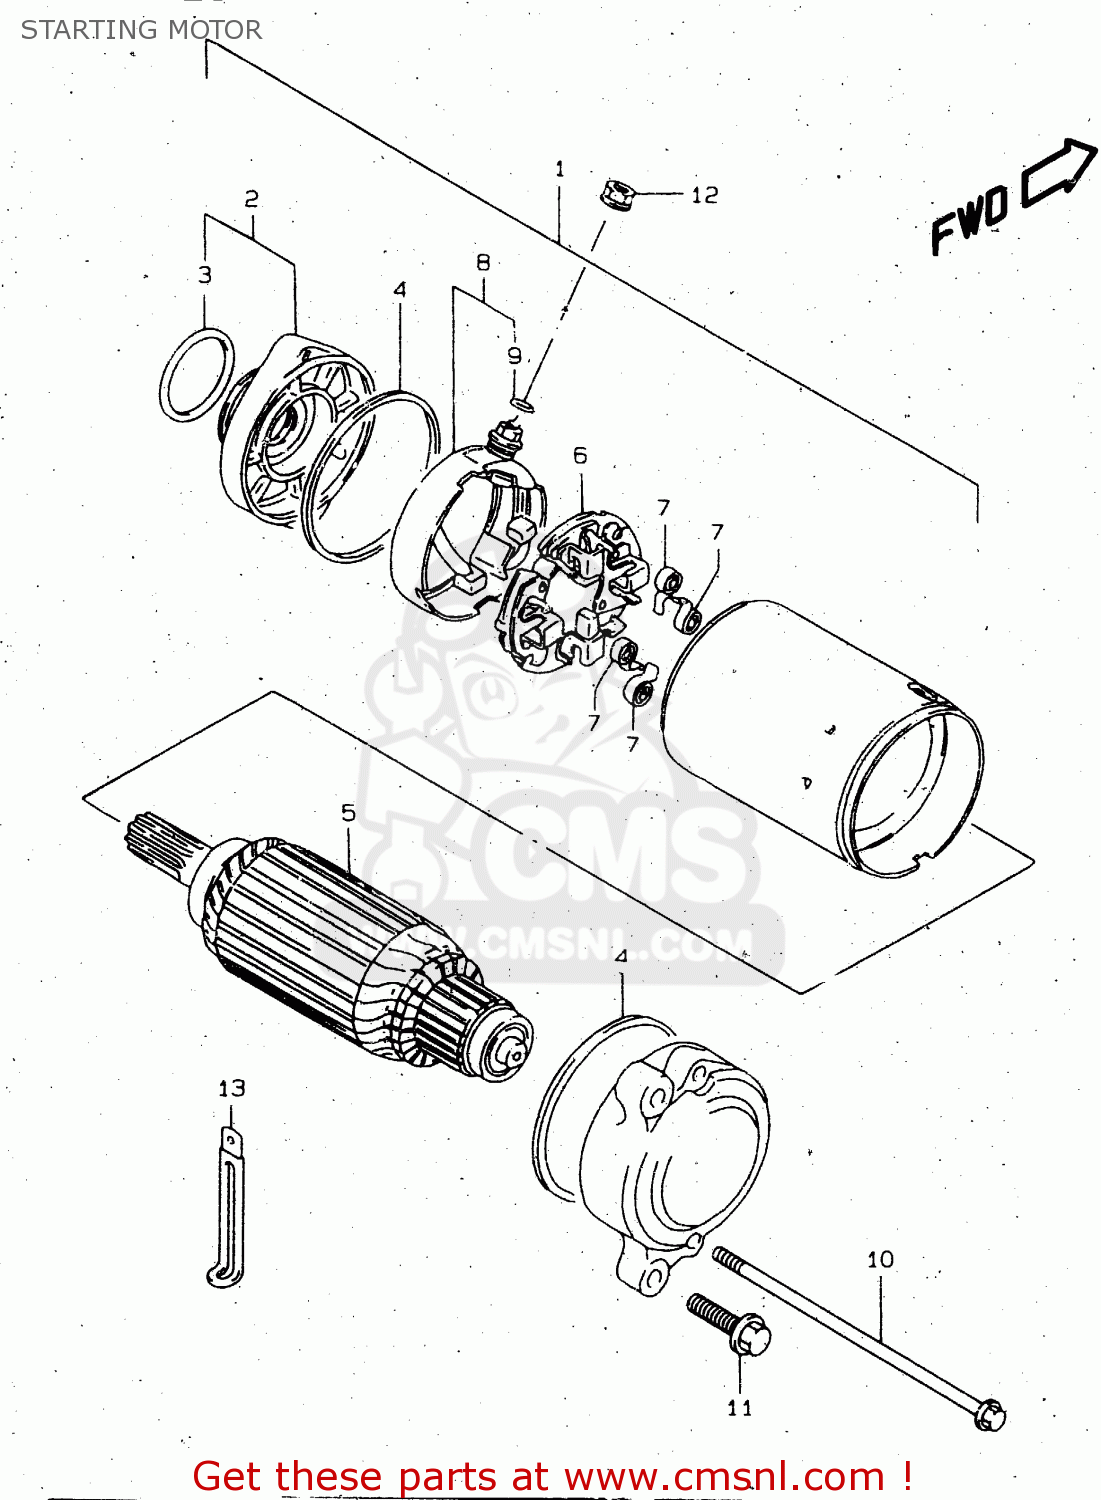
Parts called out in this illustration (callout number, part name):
1	MOTOR ASSY,STARTING
2	BRACKET SET
3	O-RING
4	SQUARE RING
5	ARMATURE
6	HOLDER SET,BRUSH
7	SPRING,BRUSH
8	TERMINAL SET,BRUSH
9	O RING
10	BOLT
11	BOLT
12	NUT
13	CLAMP(L:65)
